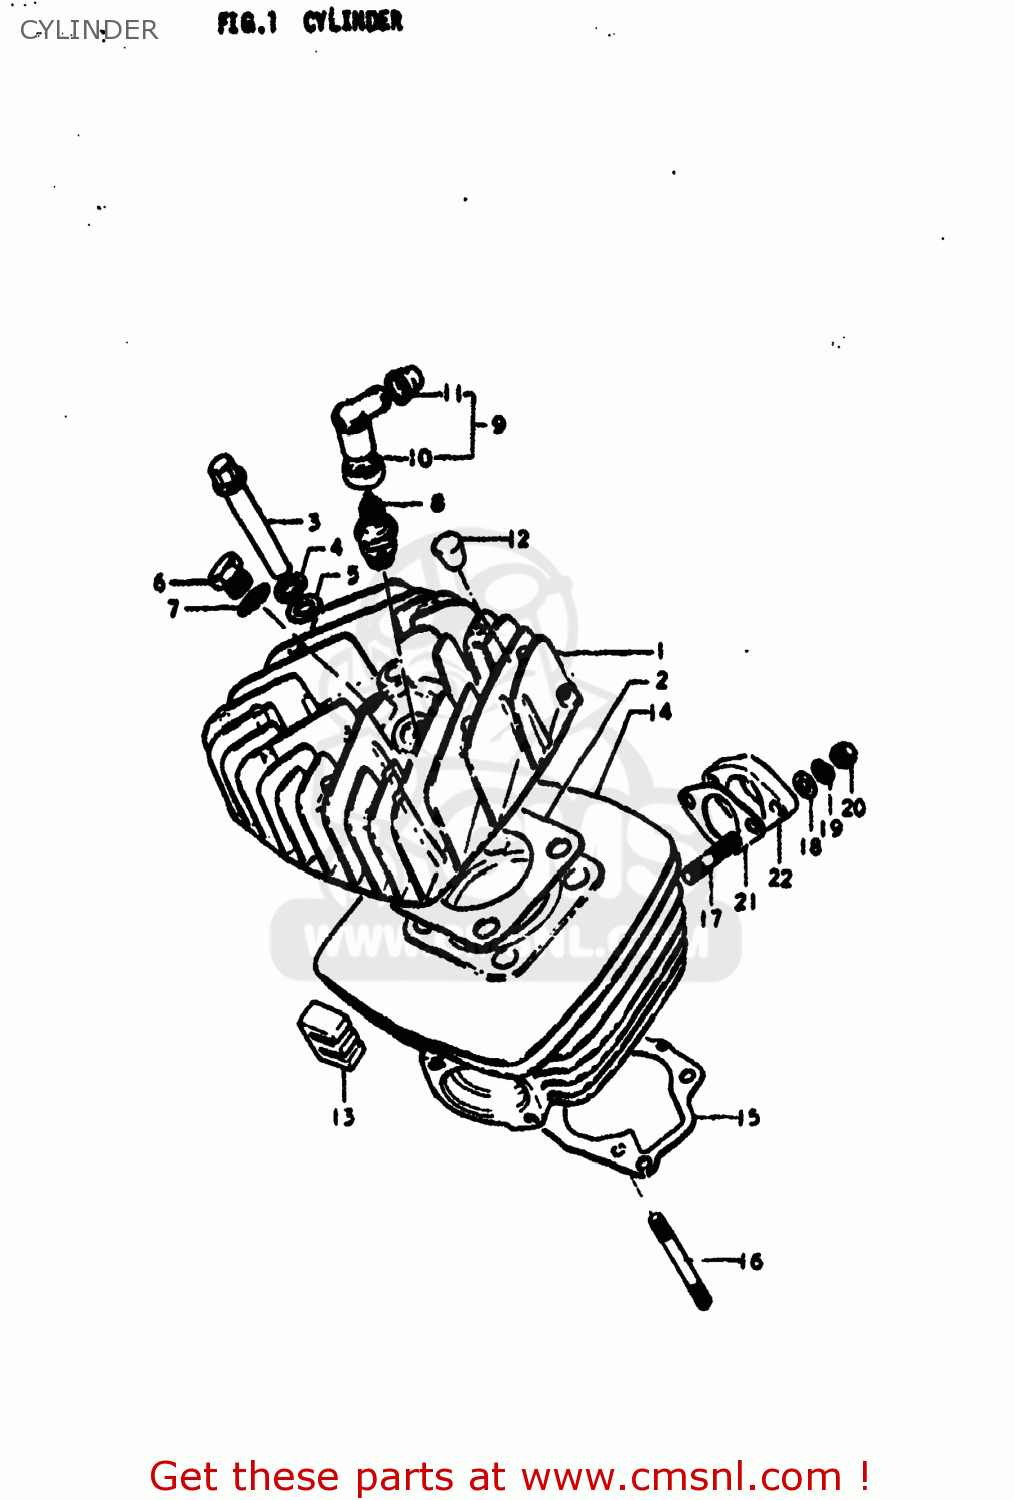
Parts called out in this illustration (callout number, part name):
1	HEAD,CYLINDER
2	GASKET,CYLINDER HEAD (NAS)
3	NUT
4	WASHER,LOCK 12
5	WASHER
6	PLUG
7	GASKET(14X19.2X2) (NAS)
8	SPARK PLUG
9	CAP,SPARK PLUG
10	SEAL,SPARK PLUG
11	SEAL,SPARK PLU
12	PAD,CYLINDER HEAD
13	PAD,CYLINDER
14	CYLINDER
15	GASKET,CYLINDER (MCA)
16	STUD 8X65
17	STUD BOLT
18	WASHER
19	LOCK WASHER
20	NUT
21	GASKET,CARBURETOR (MCA)
22	GASKET,CARBURETOR INSULATOR (NAS)
